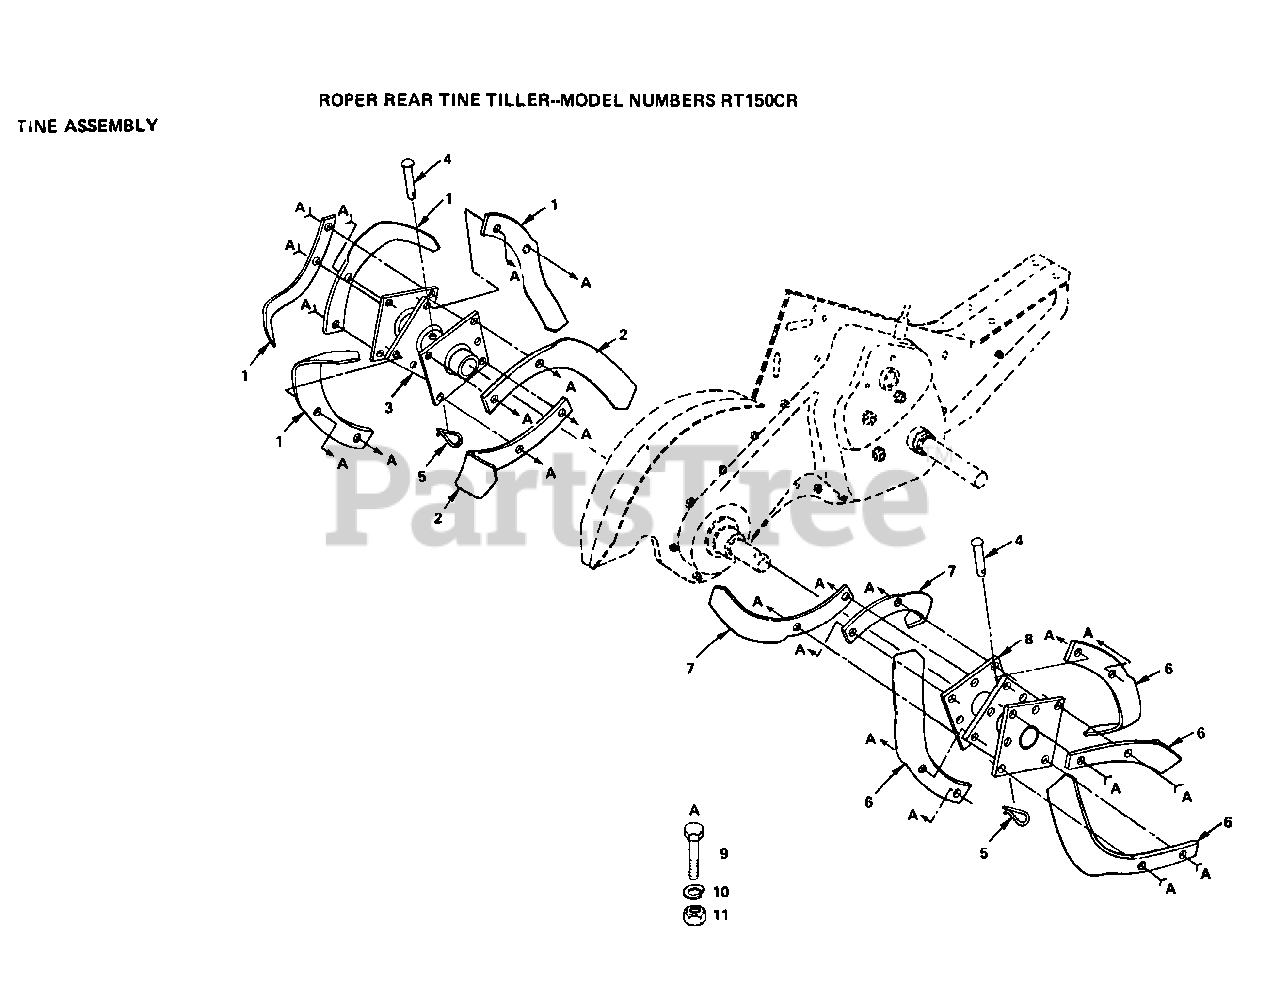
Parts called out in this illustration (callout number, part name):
2	"TINE.LH.12"""
3	TINE ASSY LH CRT
4	RIVET.PAN HD.1.75
5	RETAINER.SPRING
7	"TINE.RH.12"""
8	TINE ASSY RH CRT
9	BOLT
10	LOCKWASHER
